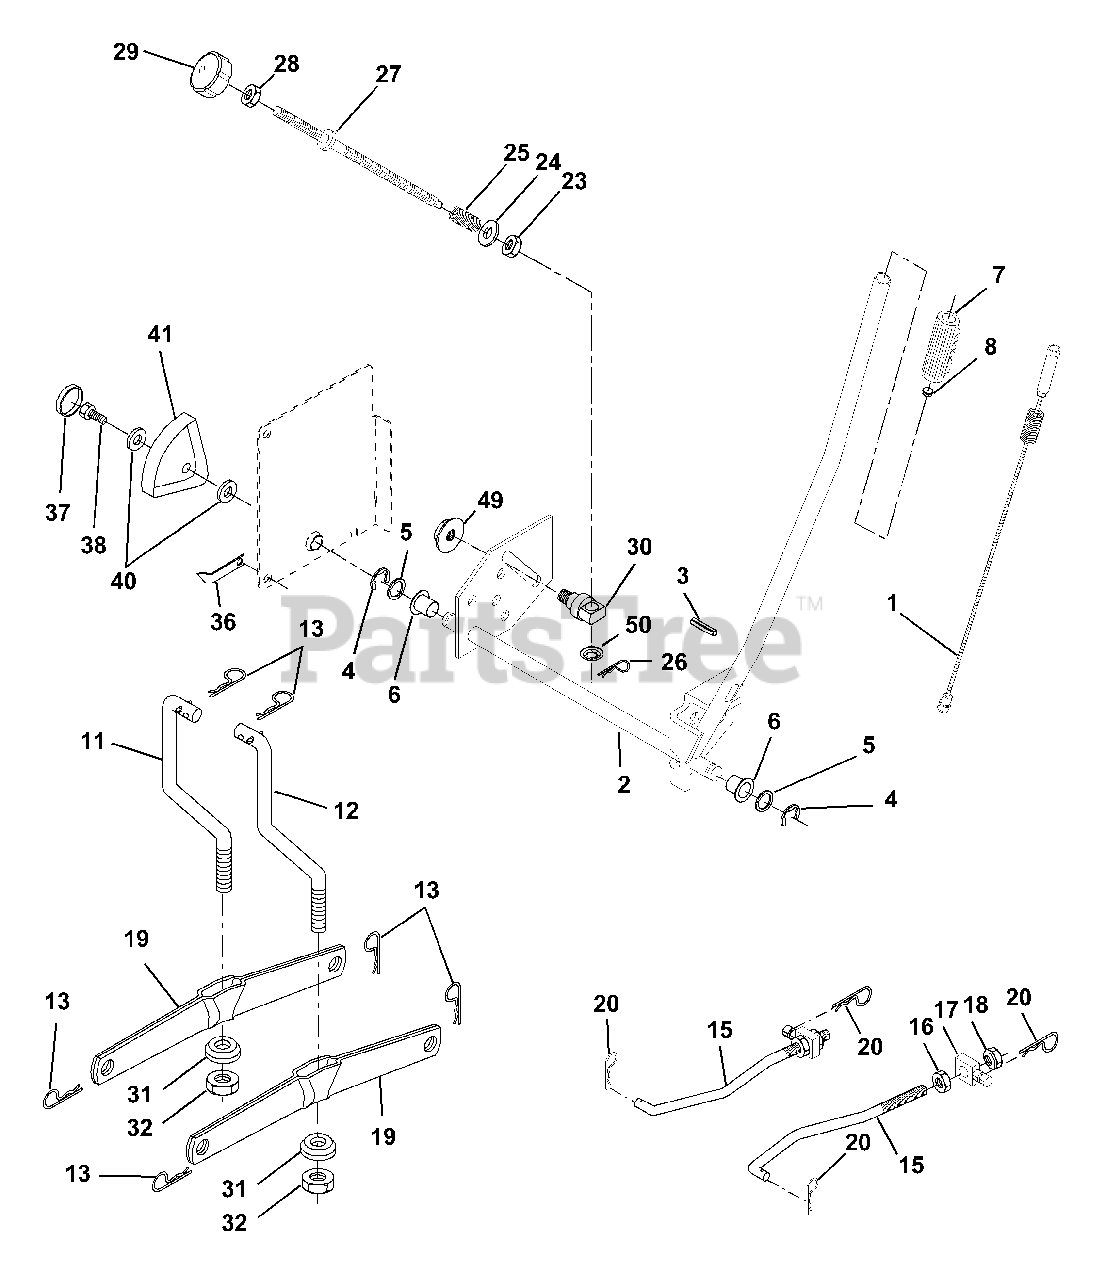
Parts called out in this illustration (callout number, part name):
1	Wire Asm Inner/Spring W/Plunger LT
2	Shaft Asm Lift RH w/Inf
3	Pin Groove 1 500 Zinc
4	E Ring #5133-62
5	Washer 21/32 X 1 X 21 Ga
6	Bearing Nylon Blk 629 Id
7	Grip Handle Fluted Blk
8	Button Plunger Black
11	Link Lift LH Fixed Length
12	Link Lift RH Fixed Length
13	Retainer Spring
15	Link Front
16	Nut Jam Hex 1/2-13 Unc
17	Trunnion Blk Zinc
18	Nut Lock w/Wsh 1/2-13unc
19	Arm Suspension Rear
20	Retainer Spring
23	Nut Special
24	Washer 13/32 X 5/8 X 16 Ga
25	Spring 2-1/8"
26	Retainer Clip
27	Rod Adj Lift Zinc 7.49 Wrk Lg
28	Nut Hex Jam 3/8-16 Unc
29	Knob Inf 3/8-16 Unc Blk W/sym
30	Trunnion Infin Height
31	Bearing Pvt Lift
32	Nut Crownlock 3/8 - 24
36	Indicator Height STLT
37	Plug Hole Blk 1.485/1.515 Dia.
38	Screw 5/16-18 x 1
40	Washer 11/32 x 1-1/2 10 Ga.
41	Scale Ind. Height Blk.
49	Nut Hex Flange Lock
50	Nut, Push Phos & Oil
